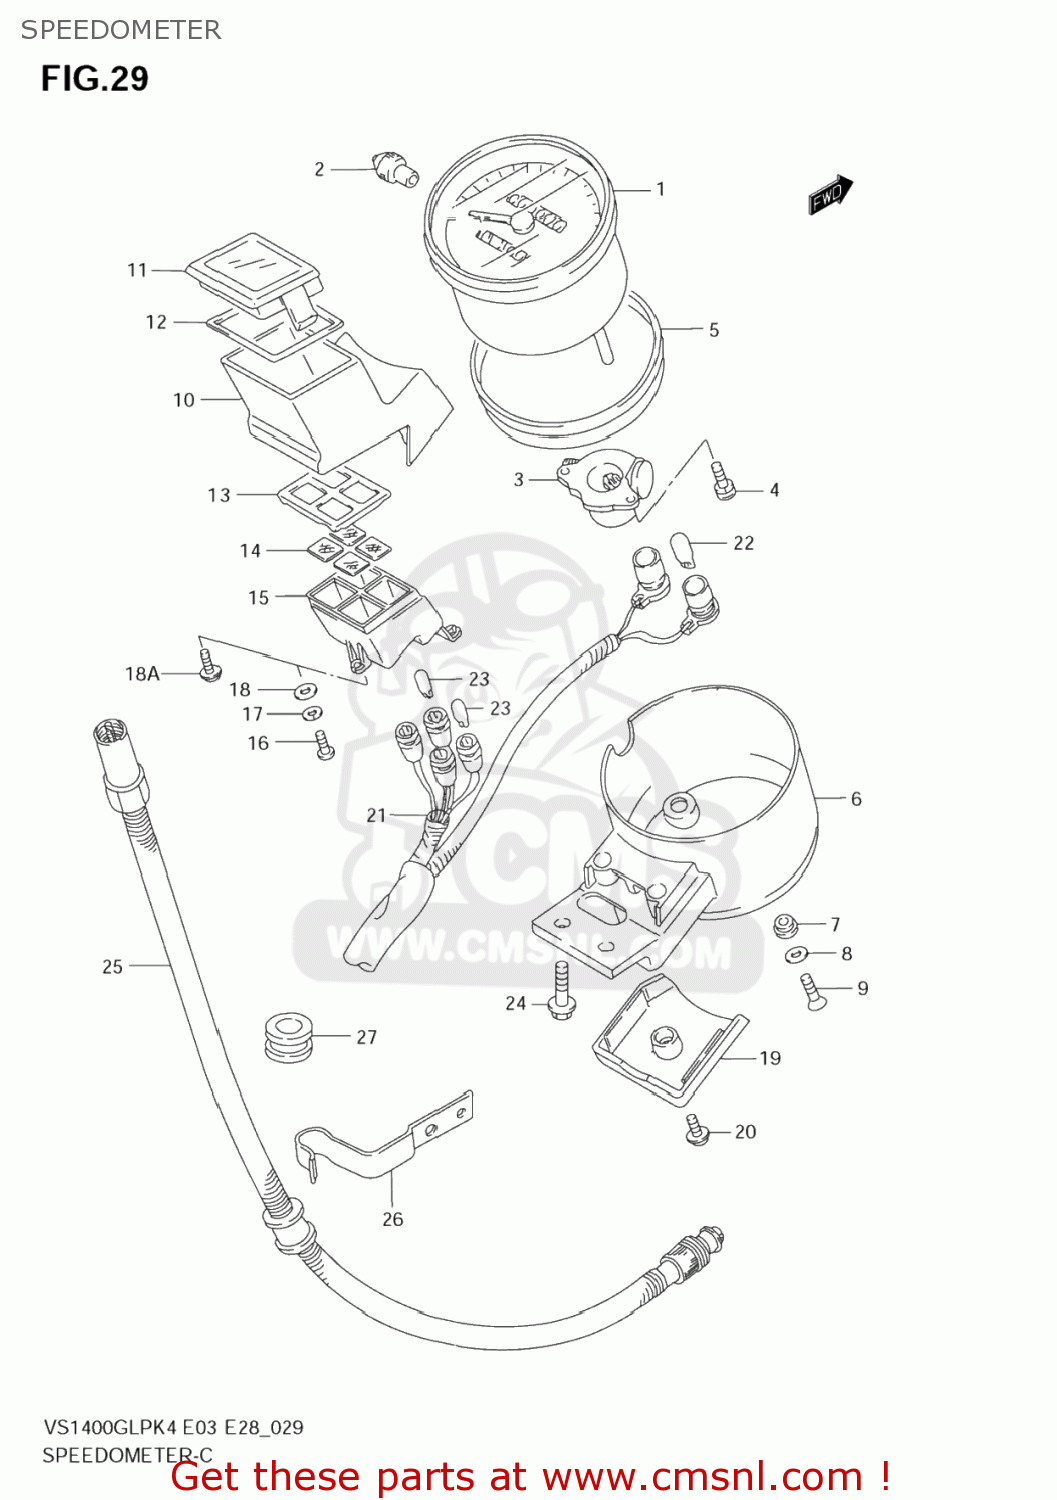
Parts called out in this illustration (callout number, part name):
1	SPEEDOMETER(KILO)
2	KNOB,TRIP
3	BOX,GEAR
4	SCREW
5	CUSHION
6	COVER,METER
7	CUSHION,METER
8	WASHER
9	SCREW
10	BOX,PILOT
11	LENS,PILOT BOX
12	CUSHION
13	PLATE,PILOT LENS
14	LENS SET,PILOT LAMP
15	CASE,PILOT LAMP
16	SCREW
17	WASHER,LOCK
18	WASHER
18A	SCREW
19	COVER,PILOT BOX
20	SCREW
21	SOCKET,METER
22	BULB(12V3.4W,T10)
23	BULB(12V1.7W,T6.5)
24	SCREW
25	CABLE ASSY,SPEEDOMETER
26	GUIDE,SPEEDOMETER CABLE
27	GROMMET
